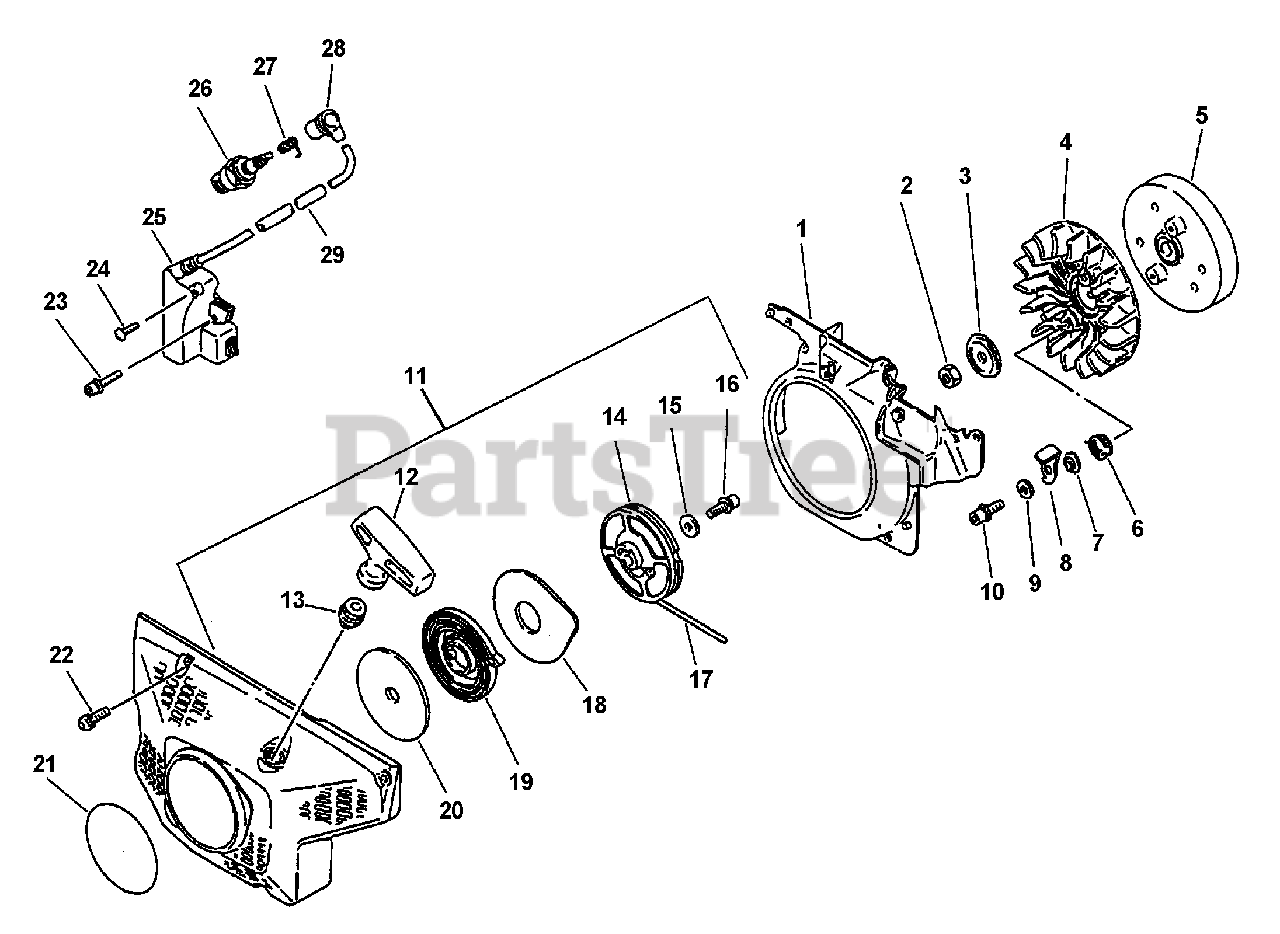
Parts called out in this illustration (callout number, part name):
1	SHIELD, FAN
3	WASHER - CUP
5	FLYWHEEL
6	SPRING, RETURN
8	PAWL, STARTER
9	WASHER - 5
10	SCREW - 5X14
11	STARTER ASSY
12	GRIP, STARTER
13	GUIDE, ROPE
14	REEL, ROPE
15	WASHER - 5
16	SCREW - 5X14
17	ROPE, STARTER - 4X900
18	PLATE, STARTER
19	SPRING, REWIND
20	PLATE, STARTER
21	LABEL - ECHO
22	SCREW - 5X20
23	SCREW - 4X20
24	SCREW - 4X8
25	COIL, IGNITION
26	SPARK PLUG -- BPM-6A
27	TERMINAL, SPARK PLUG CAP
28	CAP, SPARK PLUG
29	TUBE
